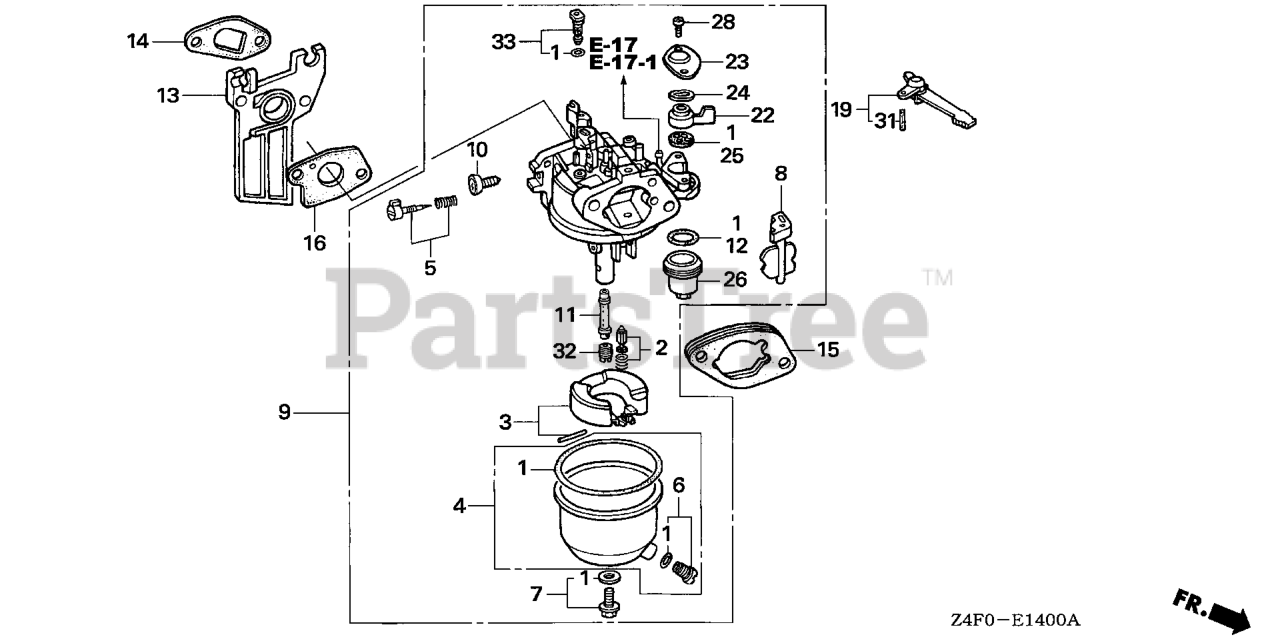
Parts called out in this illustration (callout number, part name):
1	GASKET SET
2	VALVE SET, FLOAT (CARBURETOR NO.) (SEAT NOT INCLUDED)
3	FLOAT SET
4	CHAMBER SET, FLOAT (CARBURETOR NO.)
5	SCREW SET (Honda Code 4219879). (CARBURETOR NO.)
6	SCREW SET, DRAIN (Honda Code 1672187). (CARBURETOR NO.)
7	SCREW SET B
7	SCREW SET
8	CHOKE SET
9	CARBURETOR ASSY. (BE60B B)
10	SCREW, THROTTLE STOP
11	NOZZLE, MAIN
12	GASKET, FUEL STRAINER CUP
13	INSULATOR, CARBURETOR
14	GASKET, INSULATOR
15	SPACER, CARBURETOR
16	GASKET, CARBURETOR
19	LEVER, CHOKE (STD)
22	LEVER, VALVE
23	PLATE, LEVER SETTING (CARBURETOR NO.)
24	SPRING, PETCOCK LEVER (CARBURETOR NO.)
25	GASKET, VALVE
26	CUP, FUEL STRAINER
28	SCREW, PAN (3X6)
31	PIN, SPRING (2X12)
32	JET, MAIN (#55) (CARBURETOR NO.) Use up to Engine SN BE03A J.
32	JET, MAIN (#58) Use from Engine SN BE30B E.
32	JET, MAIN (#60)
33	JET SET, PILOT (#35)
